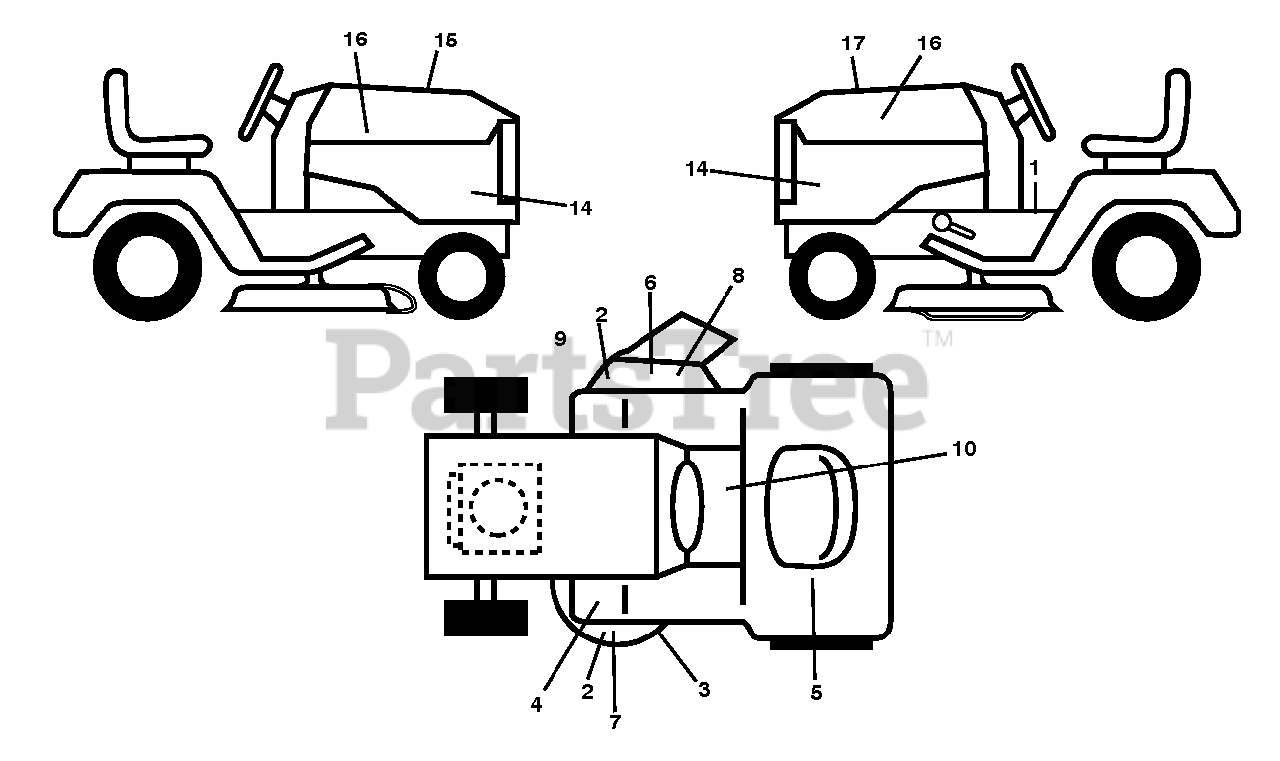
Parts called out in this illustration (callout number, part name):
1	DECAL.FENDER.WARNING.ENGLISH
2	DECAL.DECK.6MIL.EURO.NOSTEP
3	DECAL.MOWER.SCH.48/54.PREM
4	DECAL.PEDAL.HUSQ.CROWN
5	DECAL.RESERVEFUELSELCTR.ENG
6	DECAL.DECK.6MIL./DEF.SHLD.WARN
7	DECAL.HV.REINFORCED.DECKS.2012
8	DECAL, DECK DEFLECTOR, WARNING
9	DECAL BTRY SYMBOLS
10	DECAL, WARNING SPARK ARRESTOR
14	DCL.SDPNL.HUSQGT2.GT52XLS.SET
15	DECAL.WARNING.CUST.RESP.E85.
16	DECAL.BADGE.170MM.TEXTLOGO.
17	DECAL.RPL.KOH.KT7.TLB.52F.G730
